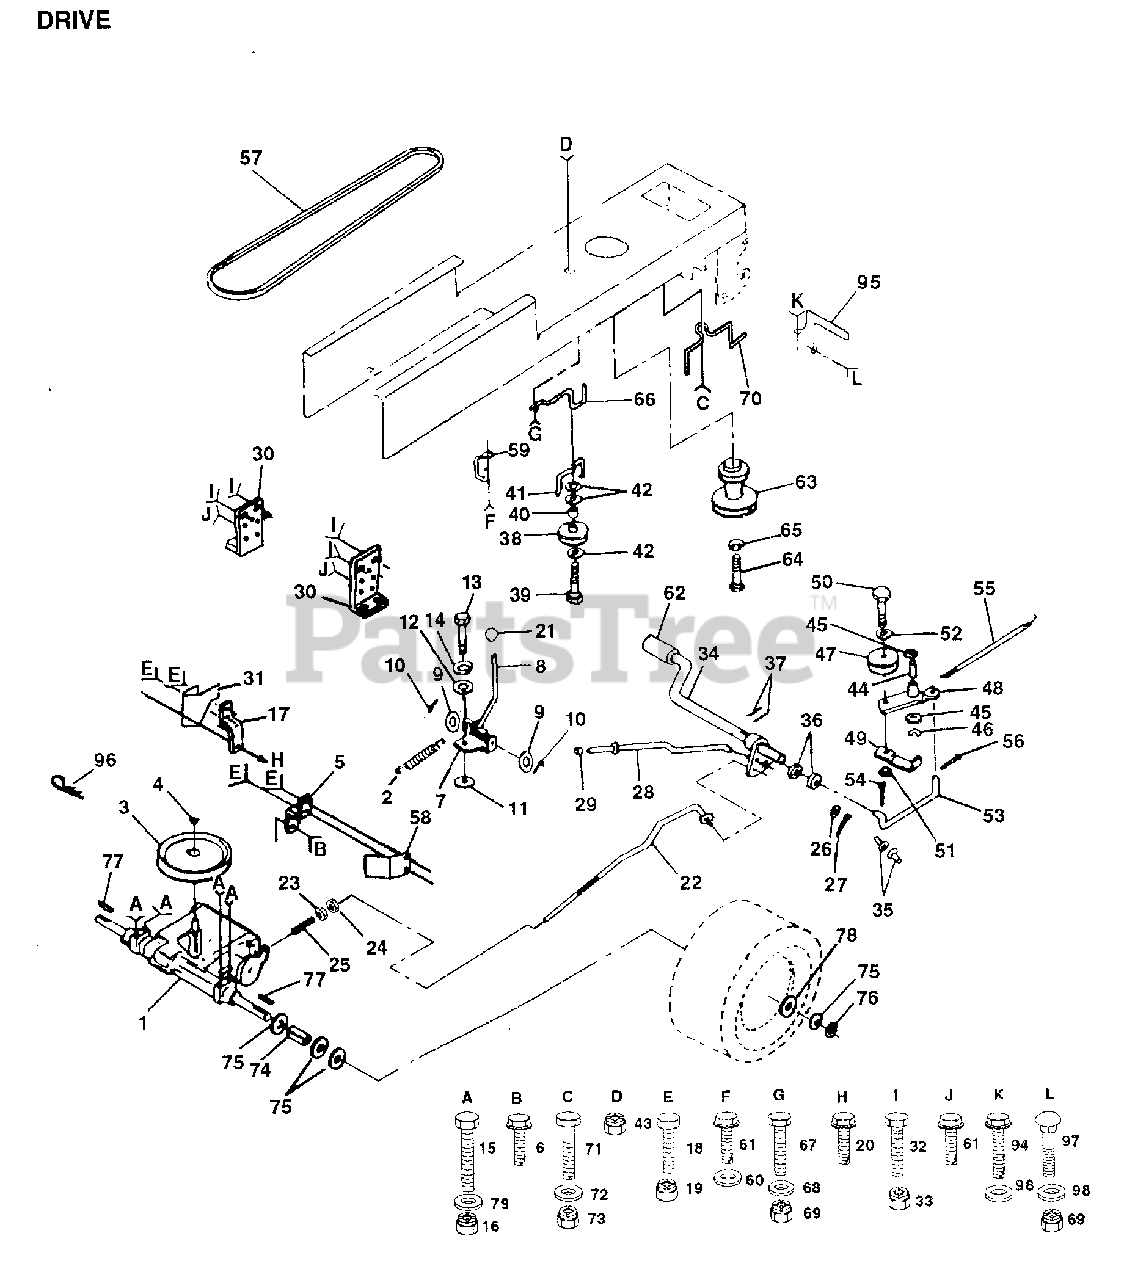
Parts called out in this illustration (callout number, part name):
3	"PULLEY,TRANSAXLE"
5	STRAP TORQUE
6	SCREW
8	SHIFT ROD
9	WASHER
10	PIN COTTER 1/8
11	WASH-SHFT PLT LT
12	WASHER LT
14	LOCKWASHER
17	STRAP TORQUE
20	SCREW
21	KNOB T (1/2-HOLE)
22	BRAKE ROD
23	NUT
24	NUT
25	SPRING ROD LT
26	WASHER
27	COTTER PIN
28	BRAKE PARK ROD
29	PLUNGER CAP T
30	TRANSAXLE MTG BKT
31	"KEEPER,BELT LH"
32	BOLT
35	NYLON BEARING
36	WASHER LT
38	PULLEY.IDLER.FLAT
39	BOLT
40	SPACER T
41	BELT KEEPER LT
42	WASHER
44	"LY, BEARING"
45	WASHER LT
46	KLIP RING
48	ARM IDLER
49	RETAIN BELT
52	WASHER
53	"LINK, CLUTCH T"
54	COTTER PIN
55	"SPRING, RETURN LT"
56	COTTER PIN
57	BELT-V
58	"KEEPER,BELT RH"
60	WASHER
61	SCREW
62	PEDAL COVER T
64	BOLT
65	LOCKWASHER
66	KEEPER.BELT.ENG.L
67	BOLT
68	WASHER
70	KEEPER BELT ENG
71	BOLT
72	WASHER
74	SPACER LT
75	WASHER
76	E-RING LT
77	SQUARE KEY
78	WASHER
79	WASHER M
94	SCREW GTV
95	MUFFLER GUARD
96	CLIP T
97	BOLT D
98	WASHER HYT
